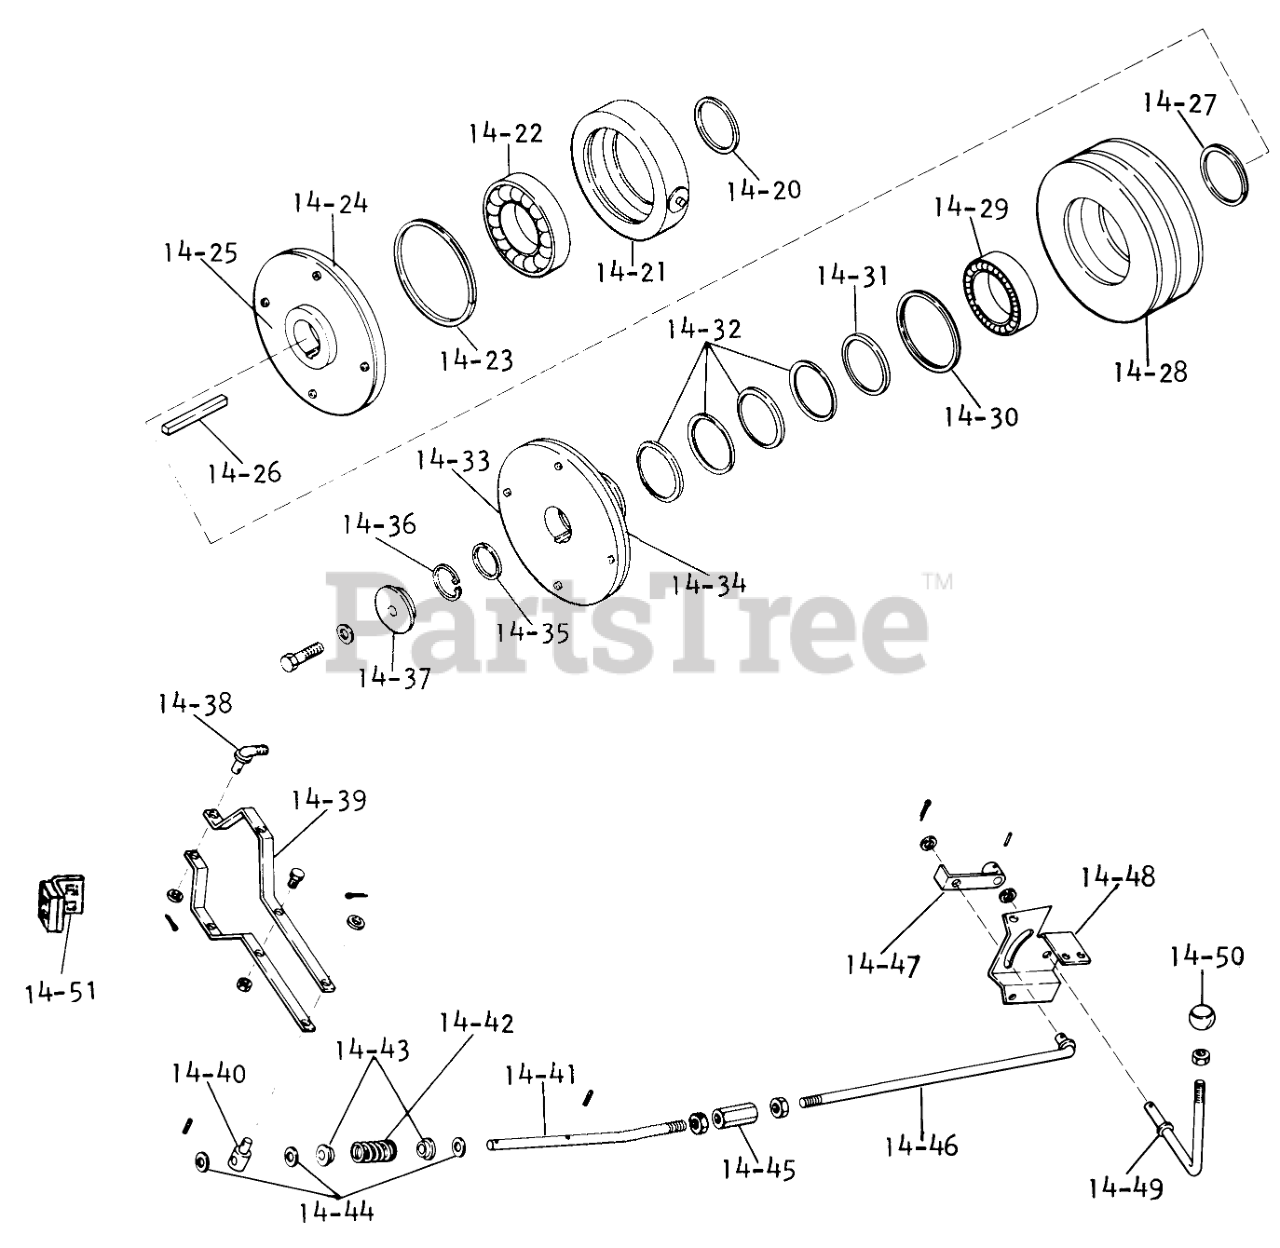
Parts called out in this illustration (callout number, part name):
14-20	RING EXTERNAL
14-21	ASSY COLLAR
14-22	BEARING
14-23	RING INTERNAL
14-24	ASSY CLUTCH PLATE
14-25	CLUTCH FACING
14-27	RING EXTERNAL
14-28	PULLEY CLUTCH
14-29	BEARING
14-30	RING INTERNAL
14-31	Washer-Spacer
14-32	SPRING WASHER
14-33	Assy-Outer Clutch
14-34	CLUTCH FACING
14-35	Washer, plain
14-36	INTERNAL RING
14-37	END CAP
14-38	ASSY HOOK
14-39	ASSY-CLUTCH BAR R
14-40	TRUNION
14-41	CLUTCH ROD
14-42	SPRING
14-43	Bushing
14-44	Washer
14-45	TURN BUCKLE NUT
14-46	Assy-Clutch Rod
14-47	ARM CLUTCH ENGAGE
14-48	Bracket
14-49	ASSY CLUTCH HANDLE
14-51	ASM CLUTCH BRAKE
